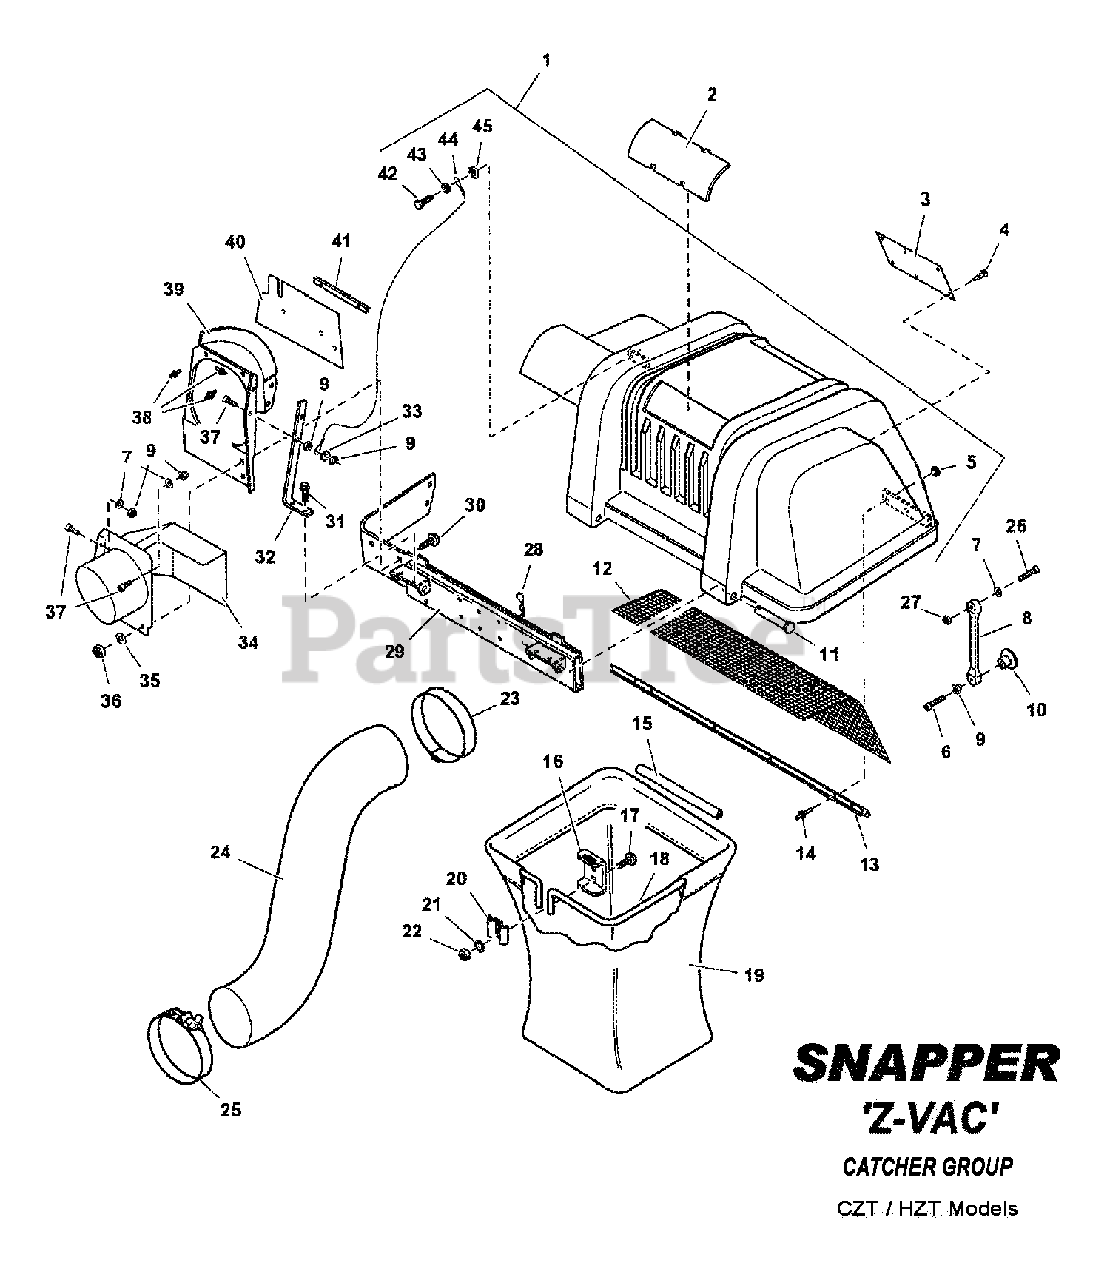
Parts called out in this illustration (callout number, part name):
1	ASSEMBLY, 2 Bag Cover and Screen
2	WINDOW, Cover
3	DECAL, Safety, Grass Bag
4	CLIP, Canoe
5	WASHER, .188 Rivet
6	SCREW, #10-32 x 1-1/2 Hex Washer Head Machine w/Nylon Patch
7	WASHER, .19 x .38 x .06 Flat
8	STRAP, Rubber
9	NUT, #10-32 Hex Nyloc
11	PIN, Round Head
12	SCREEN
13	SEAL, Clip
14	POP RIVET, 3/16 x .265 Alum.
15	TUBE CLIP, Grass Bag
16	HANGER, Grass Bag
17	BOLT, 5/16-18 x 3/4" Square Neck Carriage, GR5
18	HOOP, Grass Bag
19	GRASS BAG
20	CLAMP, Grass Bag
21	WASHER, 5/16" Split Lock
22	NUT, 5/16-18 Hex, GR5 or B
23	HOSE CLAMP, Upper
24	HOSE, Snapper Fast Vac
25	HOSE CLAMP, Lower, Fast Vac
26	SCREW, #10-24 x 1-1/4" Hex Head Cap, GR5
27	NUT, #10-24 Hex Nyloc
28	HAIR PIN, 1.6
29	CROSS ASSEMBLY
30	BOLT, 1/4-20 x 3/4" Carriage
31	SCREW, 1/4-20 x 3/8" Hex Washer Self-Tap
32	STRAP, Tube Support
33	WASHER, .191 I.D. Flat
34	WELDMENT, Hose Adapter/Deflector
35	WASHER, 1/4" Flat
36	NUT, 1/4-20 Hex Nyloc
37	SCREW, 10F x 7/8" Pan Head Cross Recess
38	POP RIVET, 3/16"
39	SUPPORT, Tube
40	SEAL, 2 Bag Catcher
41	BRACKET, Seal
42	SCREW, #10-12 x 5/8 Hex Washer Self-Tap
43	WASHER, 1/4 Split Lock
44	CABLE, Double Loop
45	NUT, Speed
